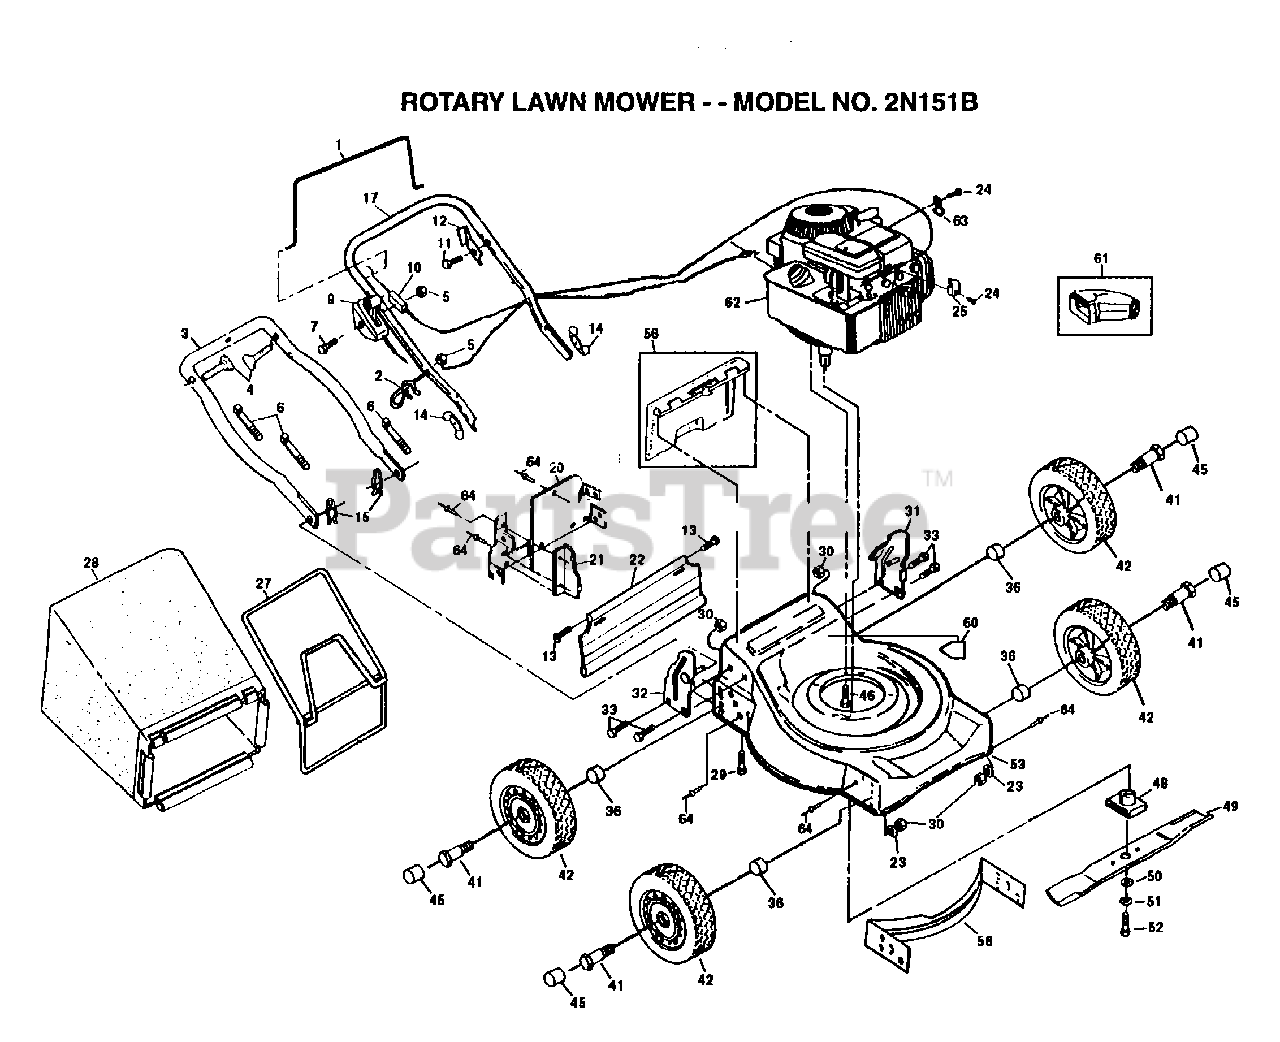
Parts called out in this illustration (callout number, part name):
1	CONTROL BAR PM
2	ROPE GUIDE
4	BOLT.HANDLE.LM
7	SCREW.HXHD.WASH.
9	CONTROL THROTTLE
10	"CABLE,ENG ZONE CO"
11	TAPPING SCREW
12	"BRKT,UPSTOP"
13	HINGE SCREW
14	"NUT,WING PM"
15	HAIRPIN COTTER
20	PLATE.BACK.20RD
22	SKIRT.REAR.20RD.
23	WASHER PM
24	SCREW PM
25	CABLE CLAMP
27	FRAME.CATCHER.ASM
28	GRASS BAG
29	SCREW
30	LOCKNUT PM
41	AXLE BOLT
42	WHEEL.ASM
45	HUB CAP-PLASTIC
46	SCREW
48	BLADE ADAPTOR
49	BLADE.20.MULCH.AY
50	WASHER (HARDENED)
51	LOCKWASHER
52	SCREW
56	KIT.DOOR.RR.20STL
60	DECAL HYT
63	GUIDE CLIP PM
64	BLIND RIVET
